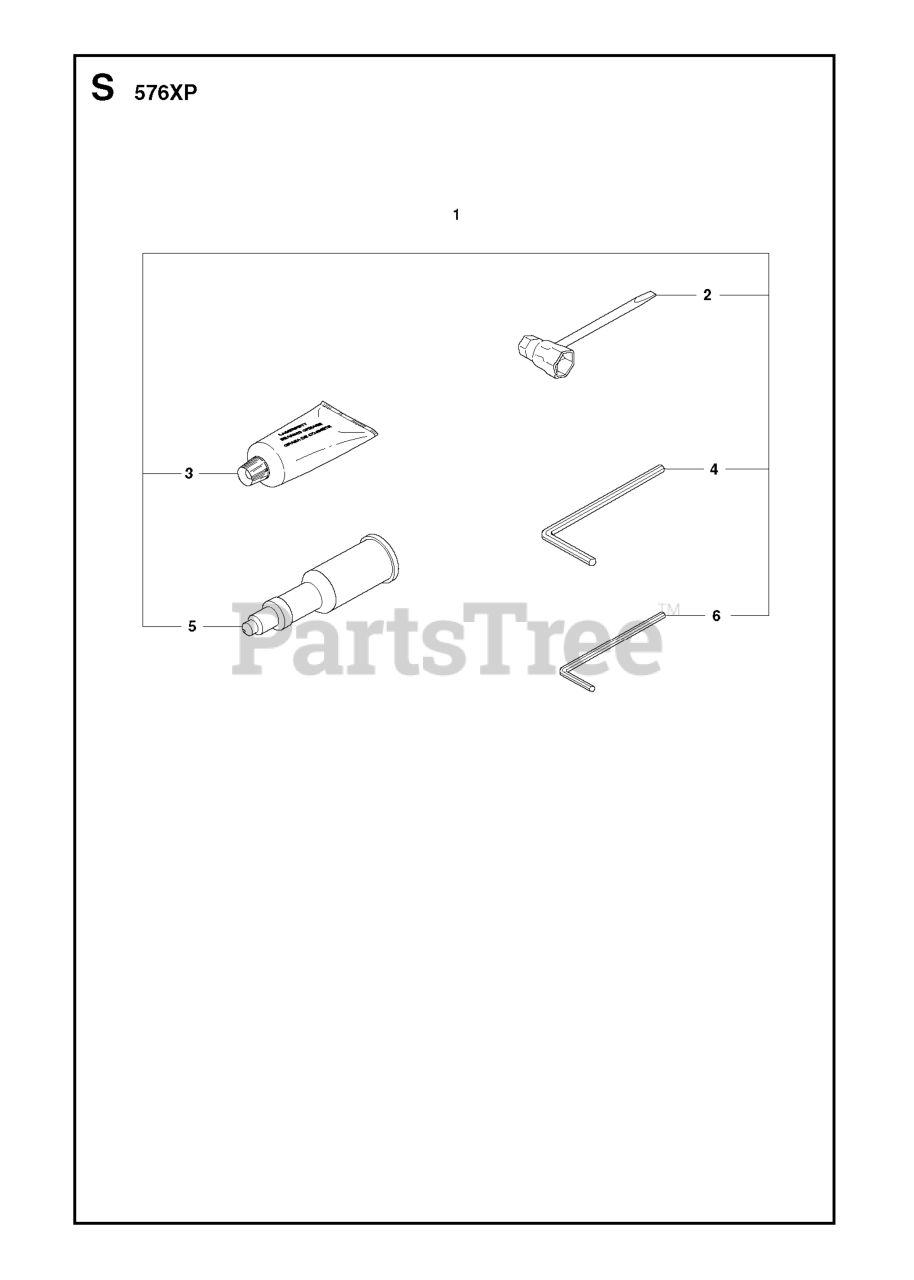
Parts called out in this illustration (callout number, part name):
1	TOOL KIT
2	COMBI TOOL
3	GREASE
5	Grease Gun
